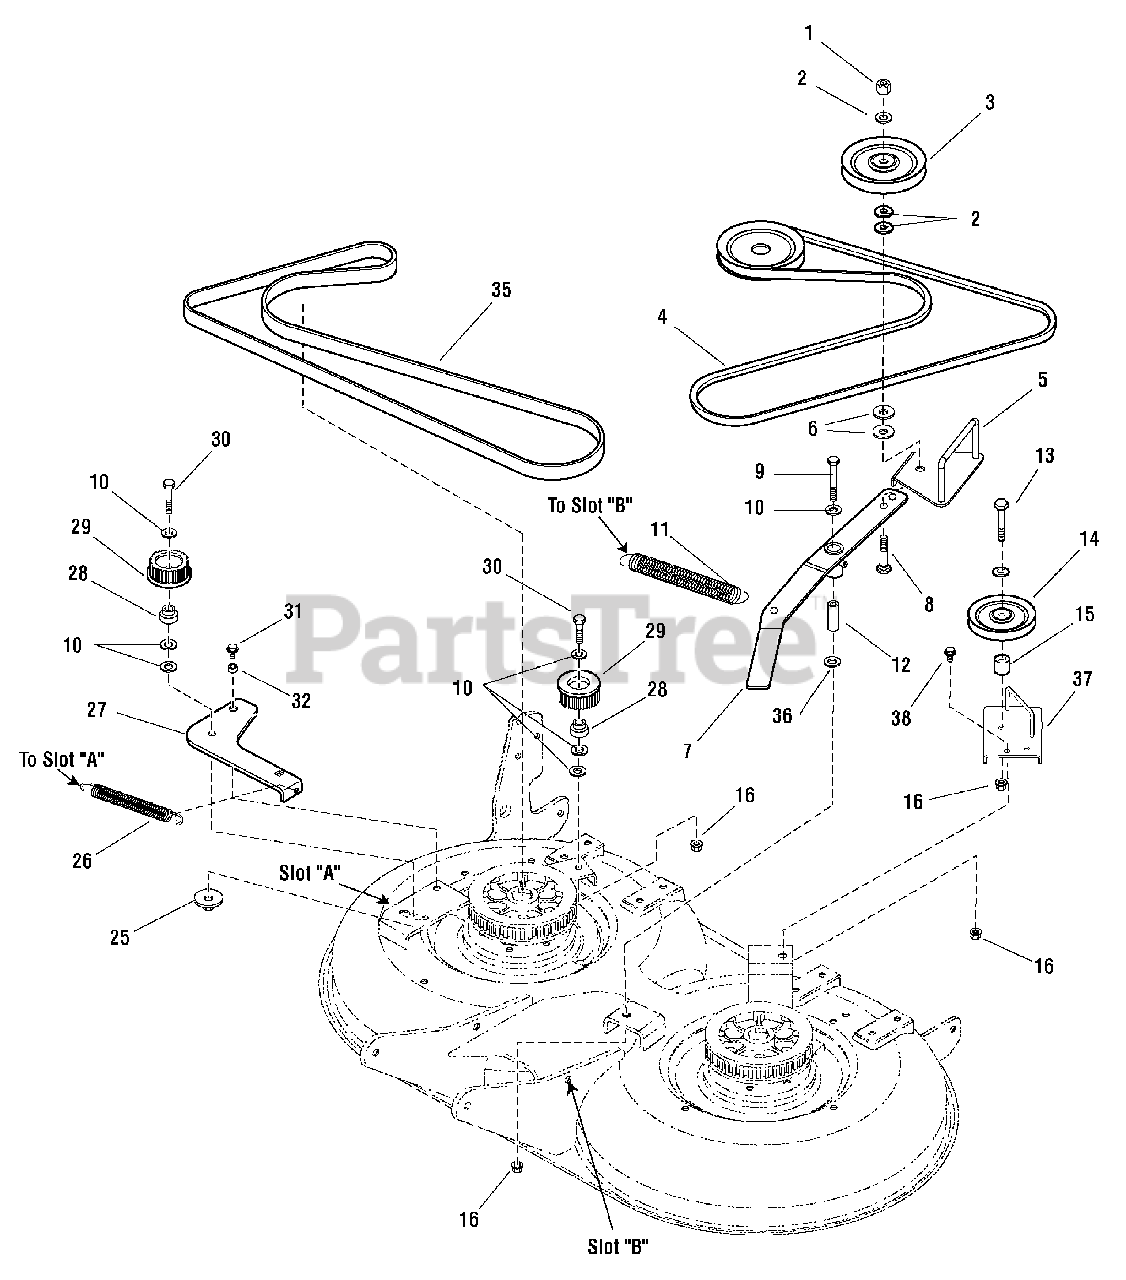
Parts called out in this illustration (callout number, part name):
1	NUT, Hex Lock Esna Light, 3/8-16
2	WASHER, 3/8
3	PULLEY, Idler
4	V-BELT, Mower Drive (82.0 EL, HA Sect.)
5	BELT GUIDE ASSY
6	WASHER
7	IDLER ASSY
8	BOLT, Carriage, 3/8-16 x 3
9	CAPSCREW, Hex, 3/8-16 x 3
10	WASHER
11	SPRING, Extension
12	SPACER,
13	CAPSCREW, Hex Head, 3/8-16 x 2-1/4
14	PULLEY
15	SPACER
16	NUT, Hex Flange Whiz Lock, Large, 3/8-16
25	WASHER & NUT ASSEMBLY, 3/8 x 1-1/2
26	SPRING, Extension
27	ARM, Idler
28	HUB, Pulley
29	PULLEY, Idler
30	BOLT, Hex Flange 3/8-16 x 2
31	CAPSCREW, Taptite Hex Washer Head, 5/16-18 x 1/2
32	SPACER
35	BELT, Timing, 38 Tooth, Arbor Drive
36	SPACER
37	PLATE ASSY, Idler
38	CAPSECREW, 3/8-16 x 3/4
